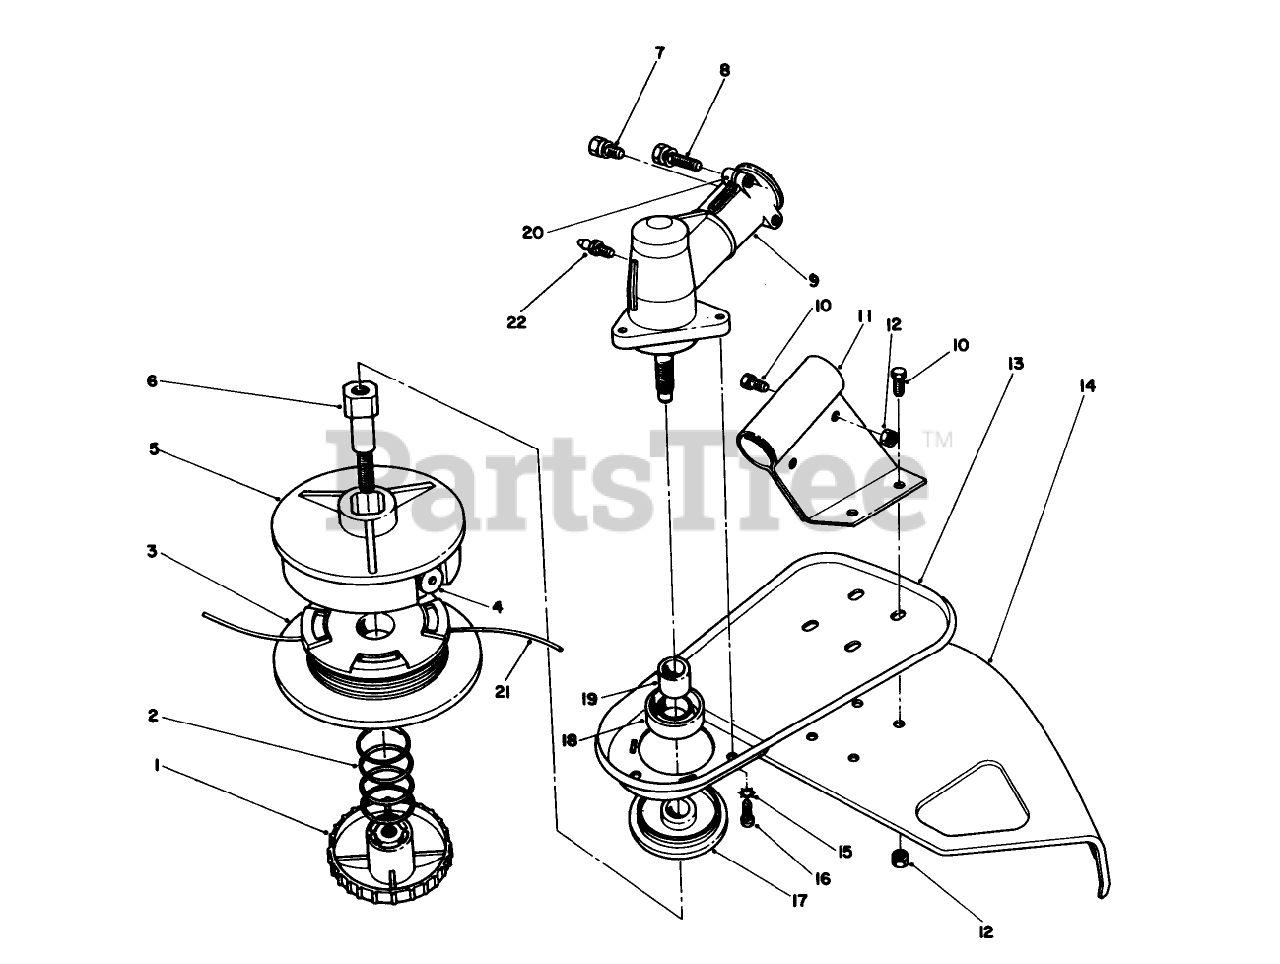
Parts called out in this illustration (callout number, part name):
3	ORDER 57-5670 HEAD
7	HHMS SCREW
9	GEARBOX
10	SCREW-SHH
11	SHIELD BRKT
12	NUT-LOCK, NI
13	SHIELD SUPPORT *R
15	WASHER-LOCK, EXT
16	SCREW
17	DUST CAP F/W
18	OIL SEAL
